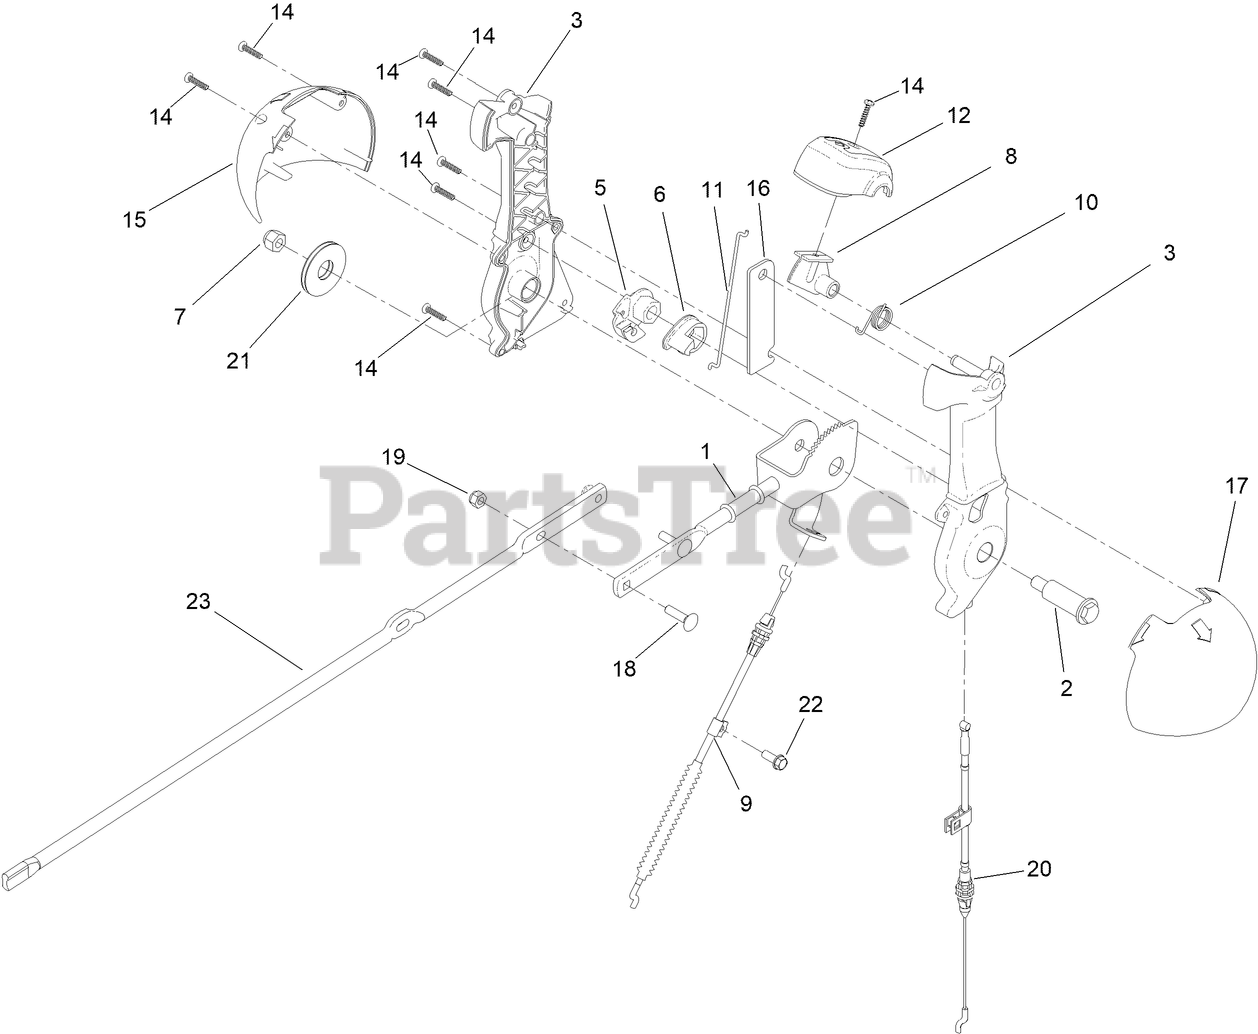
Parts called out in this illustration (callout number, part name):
1	ROD-CONTROL, CHUTE
2	SCREW-SHOULDER, HWH
3	CHUTE CONTROL LEVER ASM
5	LEVER-CABLE, DEFLECTOR
6	PAWL-LATCH
7	NUT-HEX
8	TRIGGER-LATCH
9	CABLE-CONTROL, DEFLECTOR
10	SPRING-TORSION
11	LINK-LATCH
12	CAP-LEVER
14	SCREW-PPH
15	GLOBE-QUICKSTICK, RH
16	PLATE-STIFFNER
17	GLOBE-QUICKSTICK, LH
18	BOLT-CARR
19	NUT-HEX
20	CABLE-ROTATION, CHUTE
21	WASHER-FRICTION, COMPOSITE
22	SCREW-HWH
23	ROD-CHUTE
